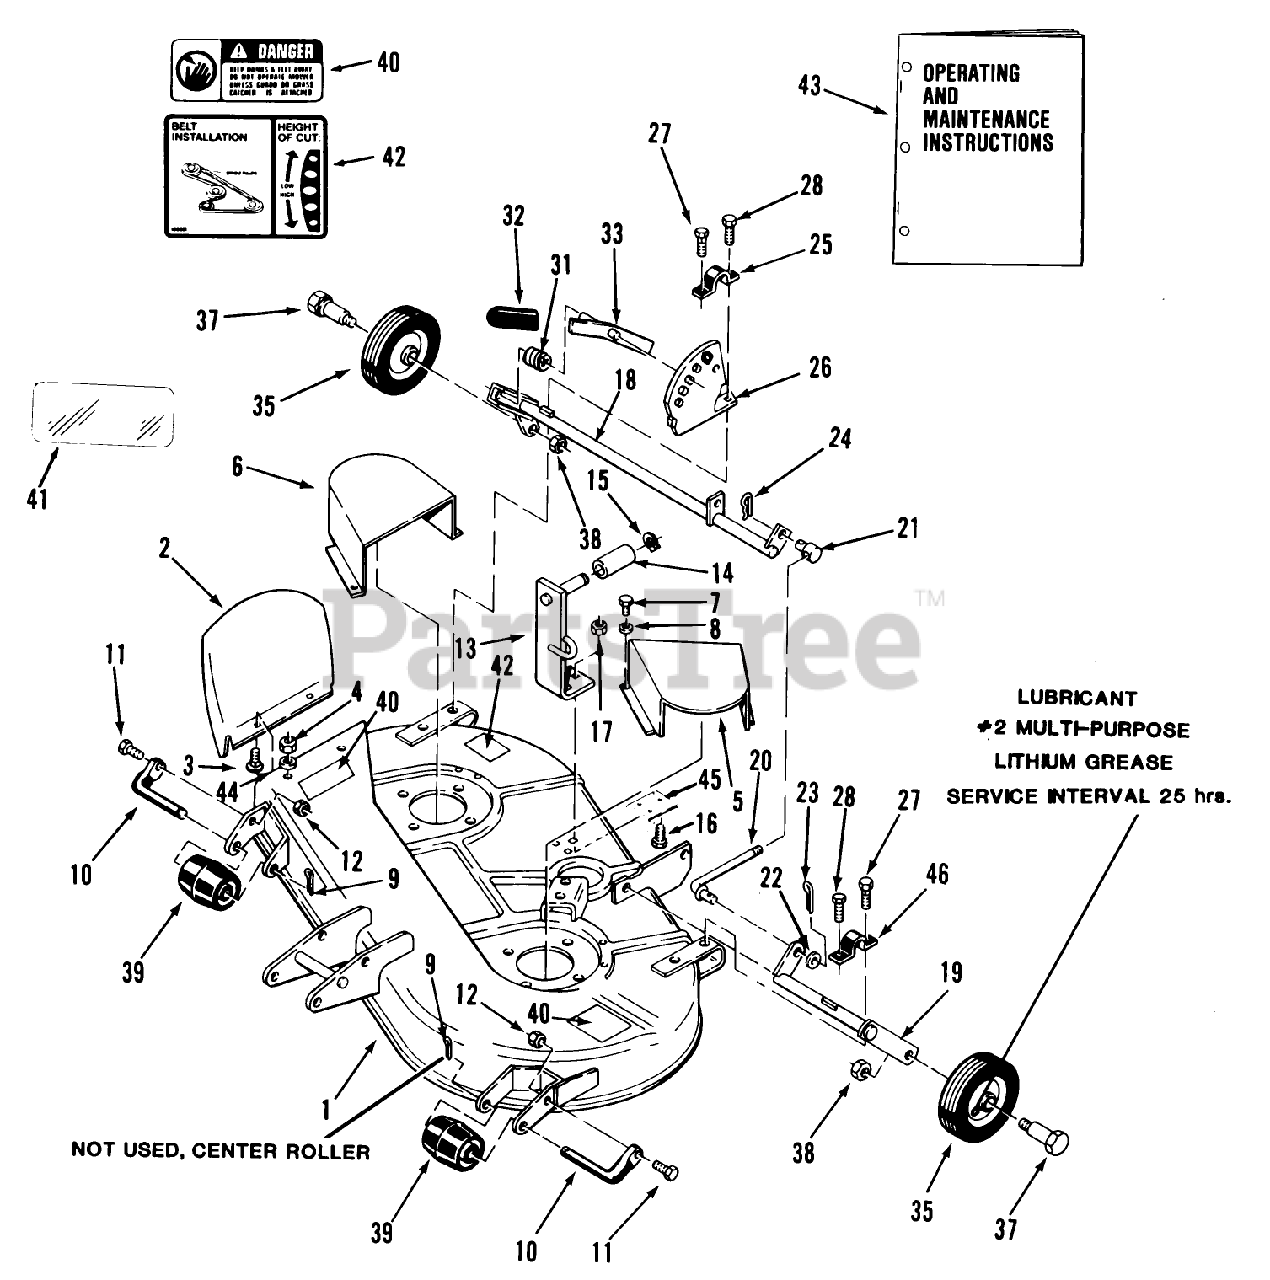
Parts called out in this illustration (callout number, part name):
6	BELT COVER-RH *R
7	Bolt
10	ROLLER-SHAFT
20	ROD CONNECTING
24	Hairpin
25	CLAMP
27	Bolt
28	Bolt
31	SPRING-COMPRESSION
35	WHEEL
37	BOLT-SHOULDER
41	DECAL-OVERLAY
43	Owner-s Maintenance Instructions
44	WASHER 5/16 SAE
46	CLAMP *B
